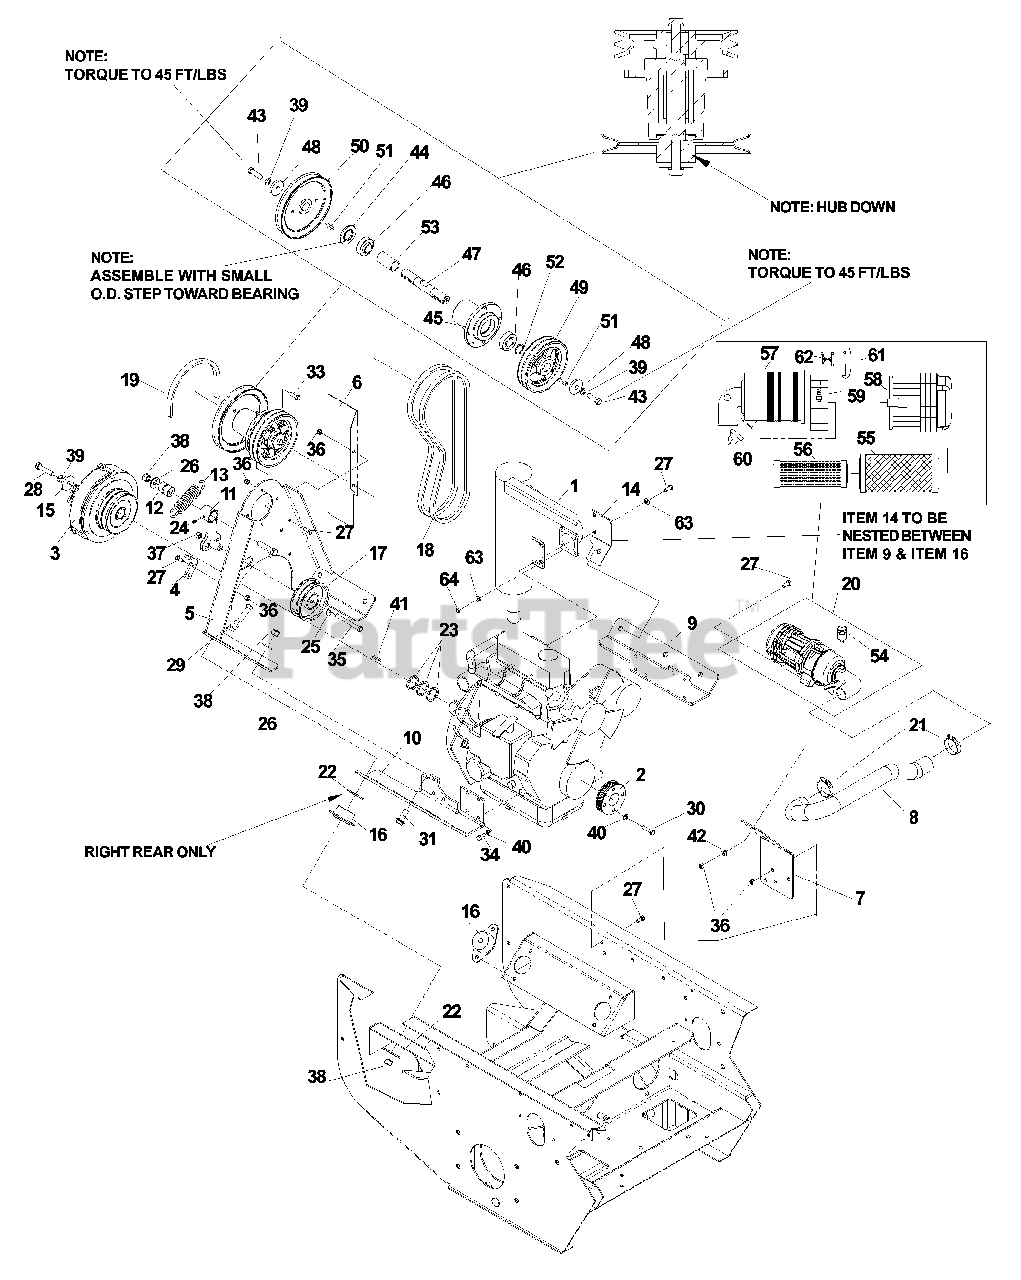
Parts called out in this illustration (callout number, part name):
1	Muffler
2	Sheave, engine
3	Clutch
4	Restraint
5	Jack mount
6	Shield, heat
7	Bracket, air filter
8	Air filter hose
9	Engine mount, left
10	Engine mount, right
14	Muffler mount
15	Washer, heavy
16	Isolator mount, engine
17	Idler
18	Belt, primary
19	Belt, mule
20	Air filter assembly
22	Isolator washer
23	Bushing, machine, 1 1/8 x 10 ga.
24	Zerk
25	Washer, 3/8, SAE
26	Washer, 1/2
27	Bolt, 5/16-18 x 3/4
28	Bolt, 7/16-20 x 2 1/2
29	Bolt, 1/2-13 x 2 3/4
30	Bolt, M8-1.25 x 35
31	Bolt, 1/2-13 x 1 1/4, serrated head
32	Bolt, 1/2-13 x 2 1/2
33	Bolt, 5/16-18 x 1
34	Bolt, M8 x 1.25 x 20
35	Bolt, 3/8-16 x 3 1/2
36	Nut, 5/16-18, nyloc
37	Nut, 3/8-16, nyloc
38	Nut, 1/2-13, nyloc
39	Lockwasher, 7/16
40	Lockwasher, 5/16
41	Key, 1/4 sq. x 1 7/8
42	Washer, 5/16
43	Bolt, 7/16-20 x 1 1/2
44	Combo spacer
46	Bearing
48	Washer, heavy
51	Key, 1/4" sq. x 1 1/8"
52	Machine bushing, 18 ga
54	Indicator, air filter
55	Air filter
56	Safety element
57	Body, 90°
58	Precleaner assembly
59	Mounting bracket
63	Washer, 3/8, spring
64	Nut, 5/16-18
